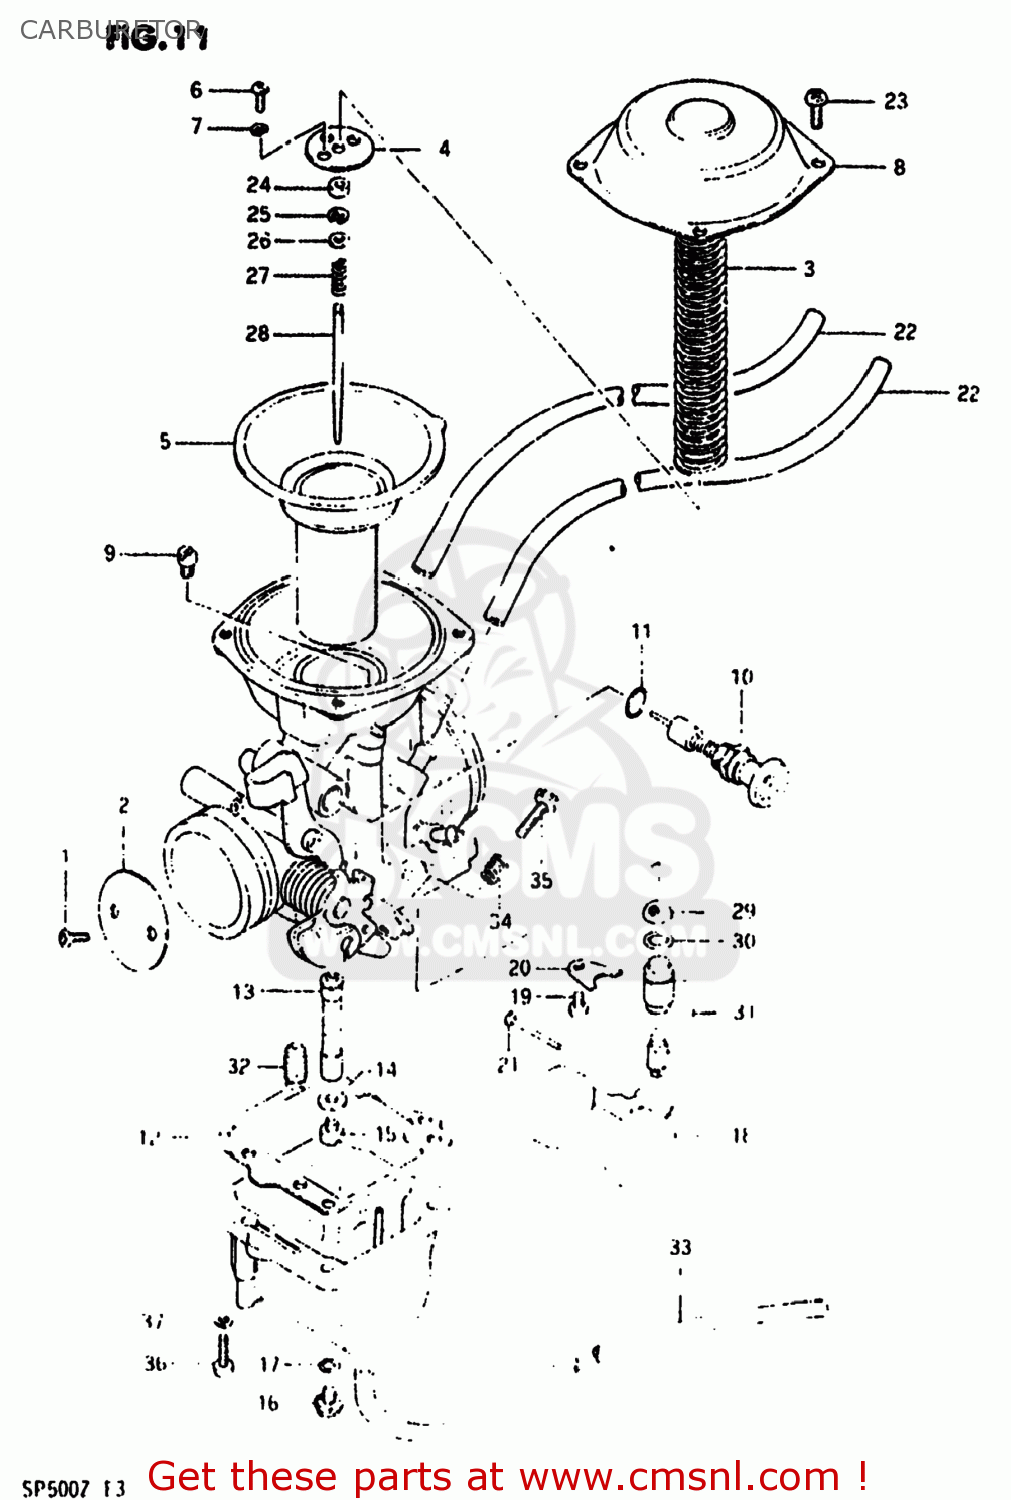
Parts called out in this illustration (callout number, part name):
1	SCREW
2	VALVE,THROTTLE (BUTTERFLY)
3	SPRING,DIAPHRAGM
4	PLATE
5	DIAPHRAGM ASSEMBLY
6	SCREW
7	LOCK WASHER
8	COVER
9	JET
10	PLUNGER
11	O RING
12	GASKET,FLOAT CHAMBER (NAS)
13	JET,NEEDLE
14	WASHER
15	JET,MAIN(140)
16	PLUG,DRAIN
17	GASKET (NAS)
18	FLOAT
19	SCREW 4X6
20	PLATE
21	PIN,FLOAT
22	HOSE
23	SCREW
24	RING
25	CLIP,NEEDLE
26	WASHER
27	SPRING
28	NEEDLE JET
29	FILTER
30	O RING
31	VALVE ASSEMBLY,NEEDLE
32	JET,PILOT
33	HOSE
34	SPRING
35	SCREW,THROTTLE STOP
36	SCREW
37	LOCK WASHER
